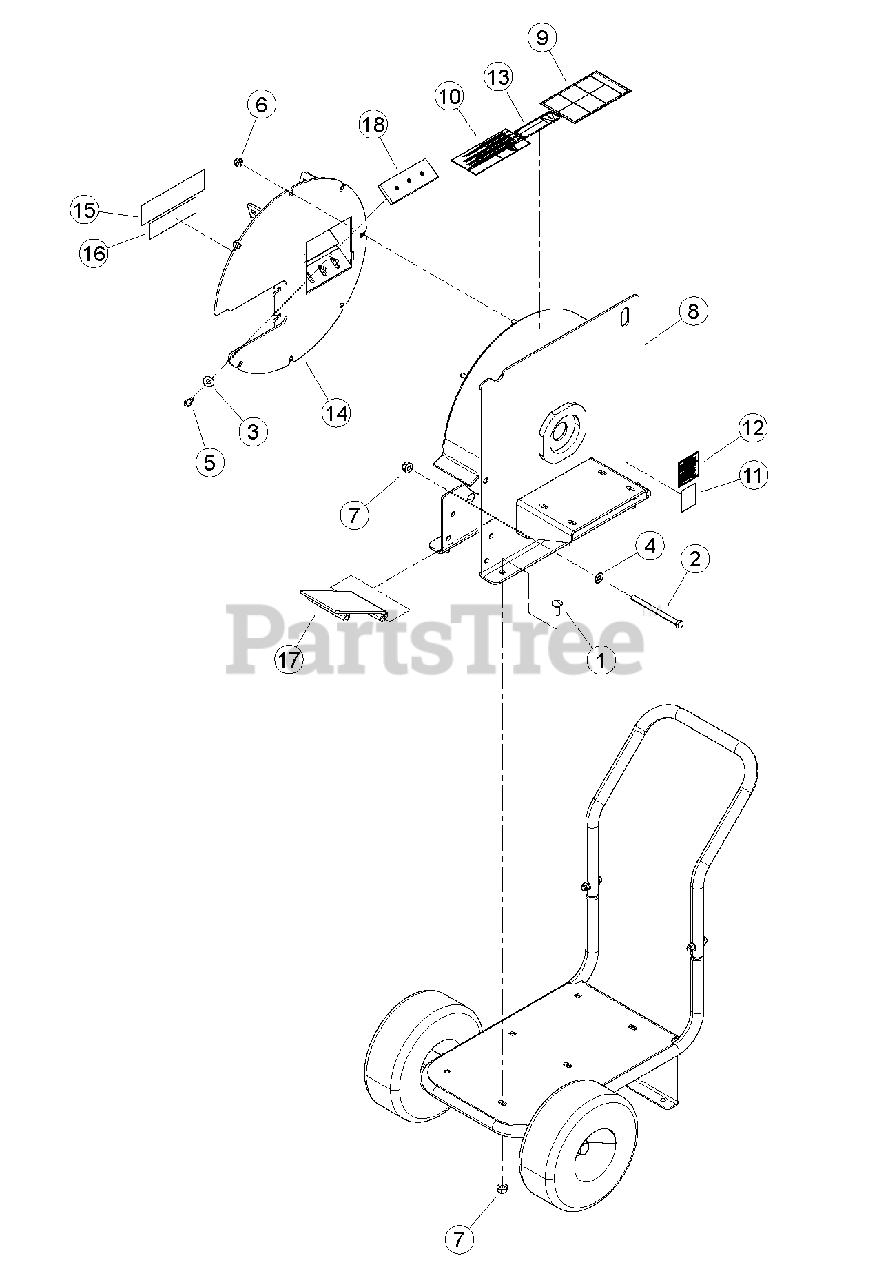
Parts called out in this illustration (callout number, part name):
1	BOLT, 3/8-16 X 1 GR5 CRG
2	BOLT, 3/8 X 5" GR5 HEX CPS ZP
3	WASHER, 5/16 FLAT
4	WASHER, 3/8 SAE FLAT ZP
5	BOLT, 5/16 X 5/8 GR5 HEX CPS ZP
6	NUT, 5/16-18 NYLOCK FLANGE
7	NUT, 3/8-16 NYLOCK FLANGE
8	ASSEMBLY, CHIPPER HOUSING
9	DECAL, OPERATING INSTRUCTIONS ISO
10	DECAL, MUTILINGUAL MANUAL
11	DECAL, ECHO BEARCAT QR CODE
12	DECAL, SPARK ARRESTOR
13	DECAL, CHOPPING CAPACITY
14	ASSEMBLY, ROTOR COVER
15	DECAL, ECHO BEARCAT 6.82 X 1.90
16	DECAL, MODEL FC200
17	WELDMENT, CHIP DEFLECTOR
18	ANVIL, CHIPPER
